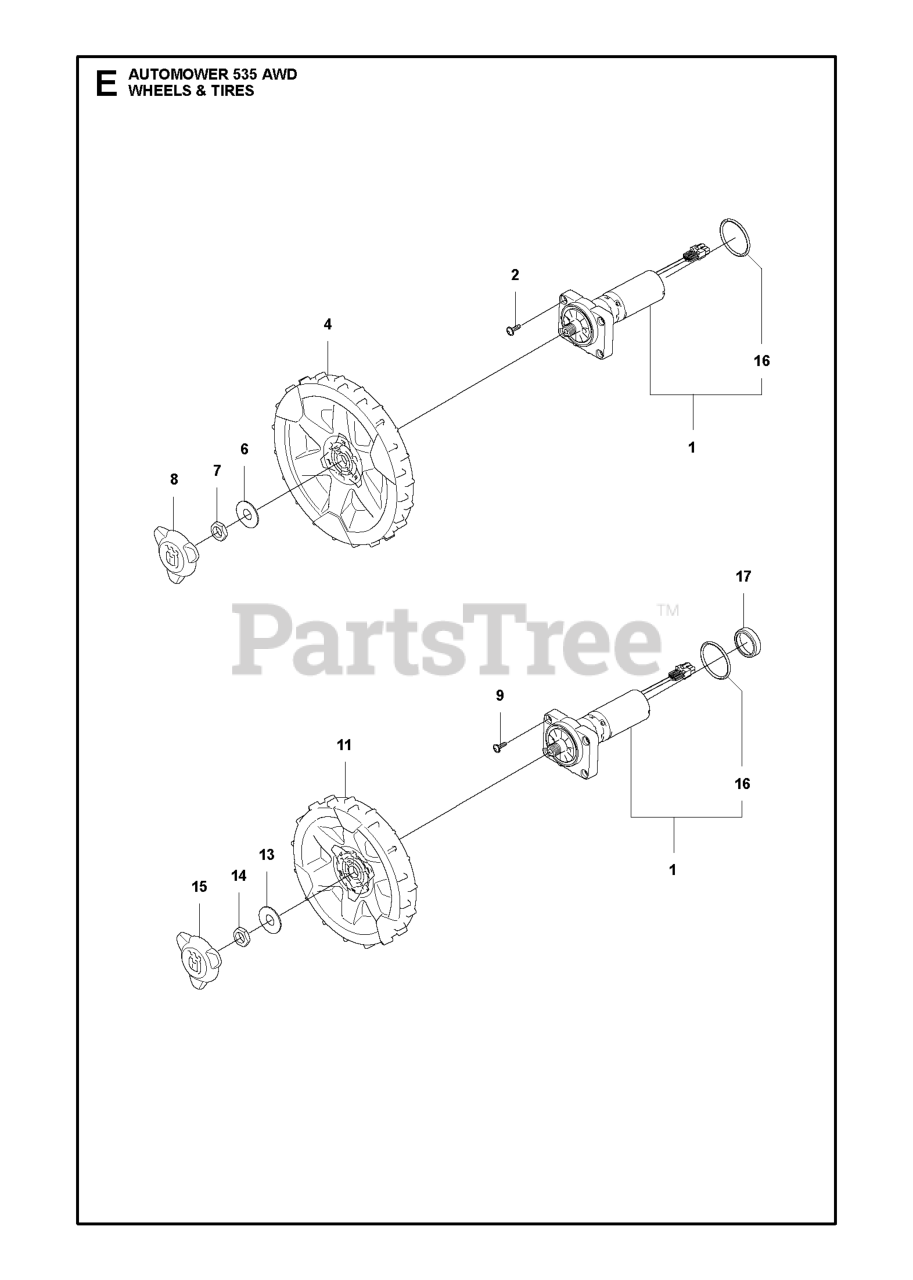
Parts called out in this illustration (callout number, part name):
2	SCREW ITXPANT
4	WHEEL ASSY D249 HVA LIGHT GREY
6	WASHER WASHER REAR WHEEL 16X40
7	HEXAGON THIN NUT
8	HUB CAP REAR WHEEL NO CENTER P
9	SCREW ITXPANT
13	WASHER WASHER REAR WHEEL 16X40
14	HEXAGON THIN NUT
15	HUB CAP REAR WHEEL NO CENTER P
16	O-RING LIGHT GREY
